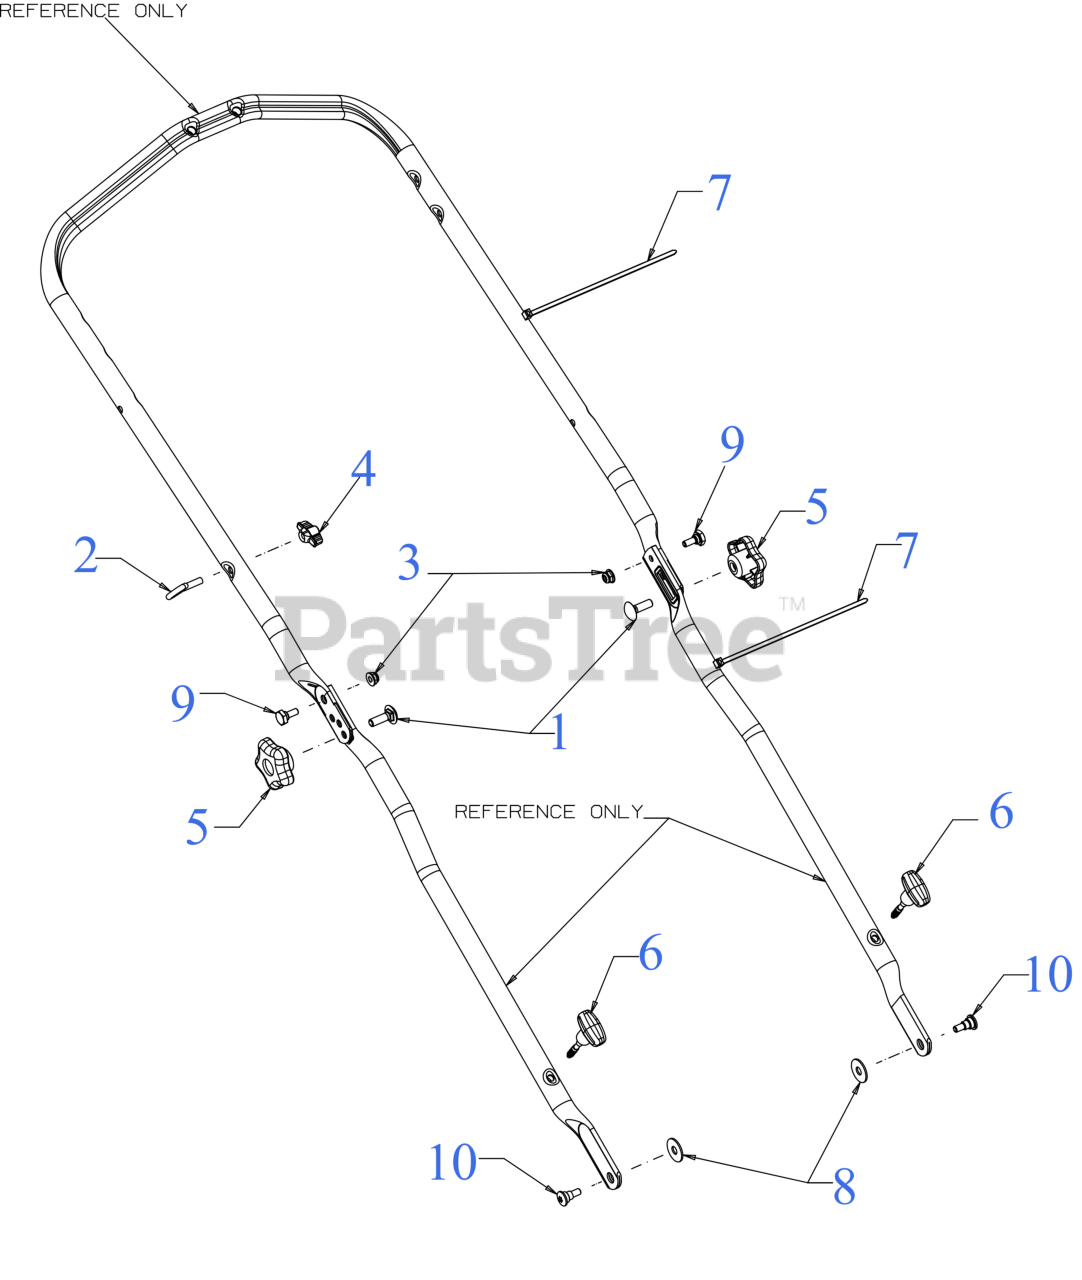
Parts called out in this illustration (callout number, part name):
1	SCREW 5/16-18 x 1.00 GR5
2	EYEBOLT 1/4-20
3	FLANGE LOCK NUT
4	HANDLE KNOB
5	STAR KNOB 5/16-18
6	WING KNOB 1/4-20 x 1.80
7	7" CABLE TIE
8	FLAT WASHER 344X1.00
9	SHOULDER SCREW
10	SHOULDER SCREW .450X .188X 1/4-20
